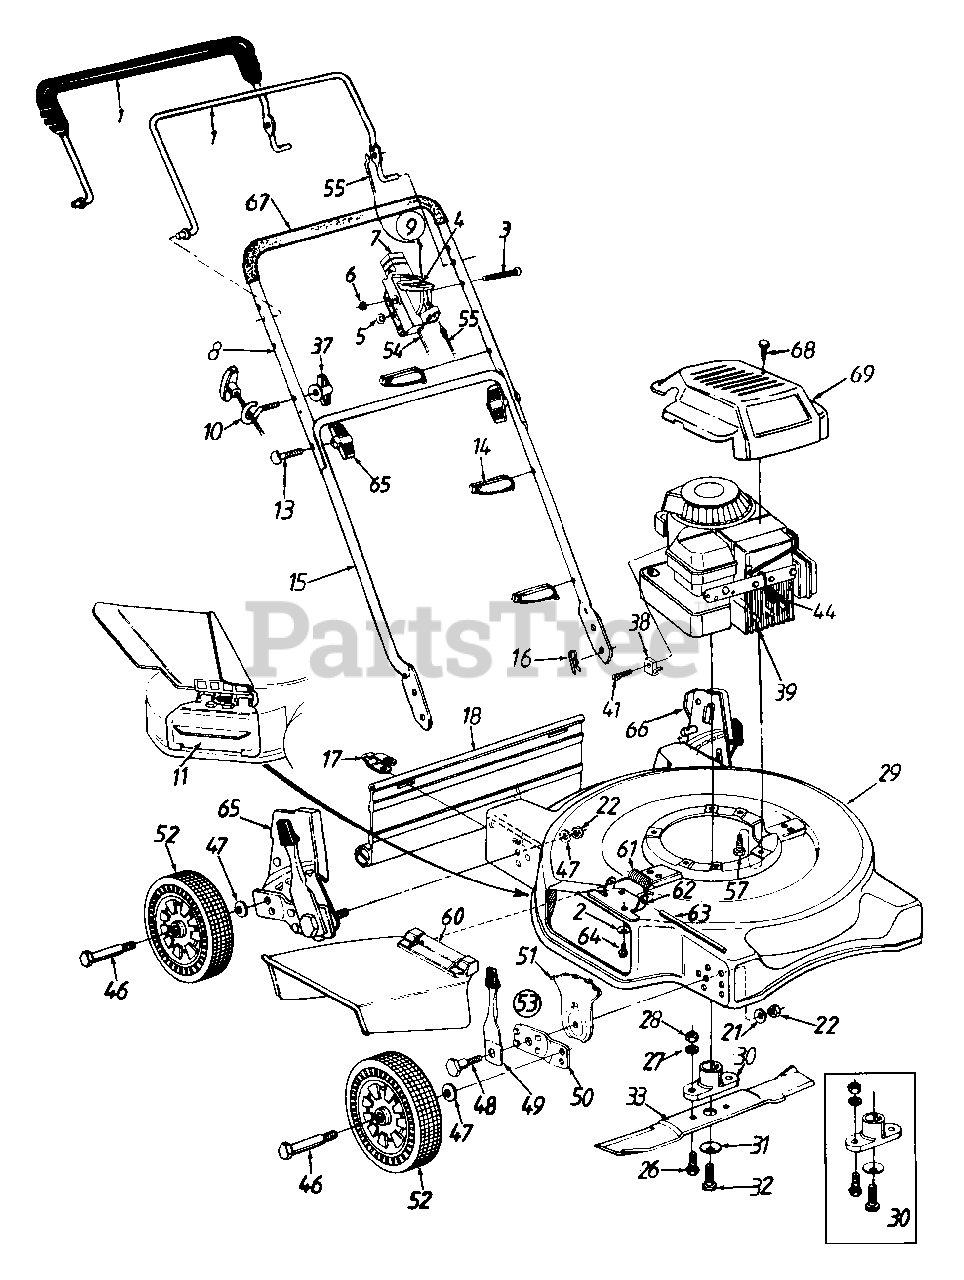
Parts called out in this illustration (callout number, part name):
1	Control Handle Ass'y. w/Plastic
2	Bell-Wash. 1/4" I.D.
3	Oval C-Sunk Mach. Scr.
4	Throttle Lever
5	Spr. Wash. .66" I.D.
6	Hex L-Nut 1/4-20 Thd.
7	Throttle Body
10	Rope Guide
13	Curved Hd. Bolt 5/16-18 x 2" Lg.
14	Cable Tie
16	Hairpin Cotter
17	Hinge Clip
18	Rear Flap
22	Hex Nut 3/8-16 Thd.
26	Hex Bolt 3/8-24 x 1" Lg.
27	L-Wash. 3/8" I.D.
28	Hex Nut 3/8-24 Thd.
31	Bell-Wash. .39" I.D.
32	Hex Bolt 3/8-24 x 1.5" Lg.
33	20" Blade
37	Wing Nut 1/4-20 Thd.
38	Cable Clamp
39	Engine
41	Hex Wash. Hd. Tap Scr. #10-32 x .62" Lg.
44	Spark Plug Boot
47	Bell-Wash. .400" I.D. x .88"
48	Shld. Bolt .50" Dia. x .357"
49	Spring Lever Ass'y. w/Knob
51	Height Adj. Plate
52	Wheel Ass'y. Comp.
53	Height Adj. Ass'y. Comp. - R.F.
54	Throttle Cable - 51"
55	Control Cable - 39"
57	Hex L-Wash. Hd. Scr. 3/8-16 x 1.0" Lg.
60	Chute Deflector Ass'y.
61	Torsion Spring
62	Adapter Plate
63	Hinge Pin
64	Hex Self-Tap Scr. 1/4-20 x .5"
67	Foam Grip
69	Engine Shroud
